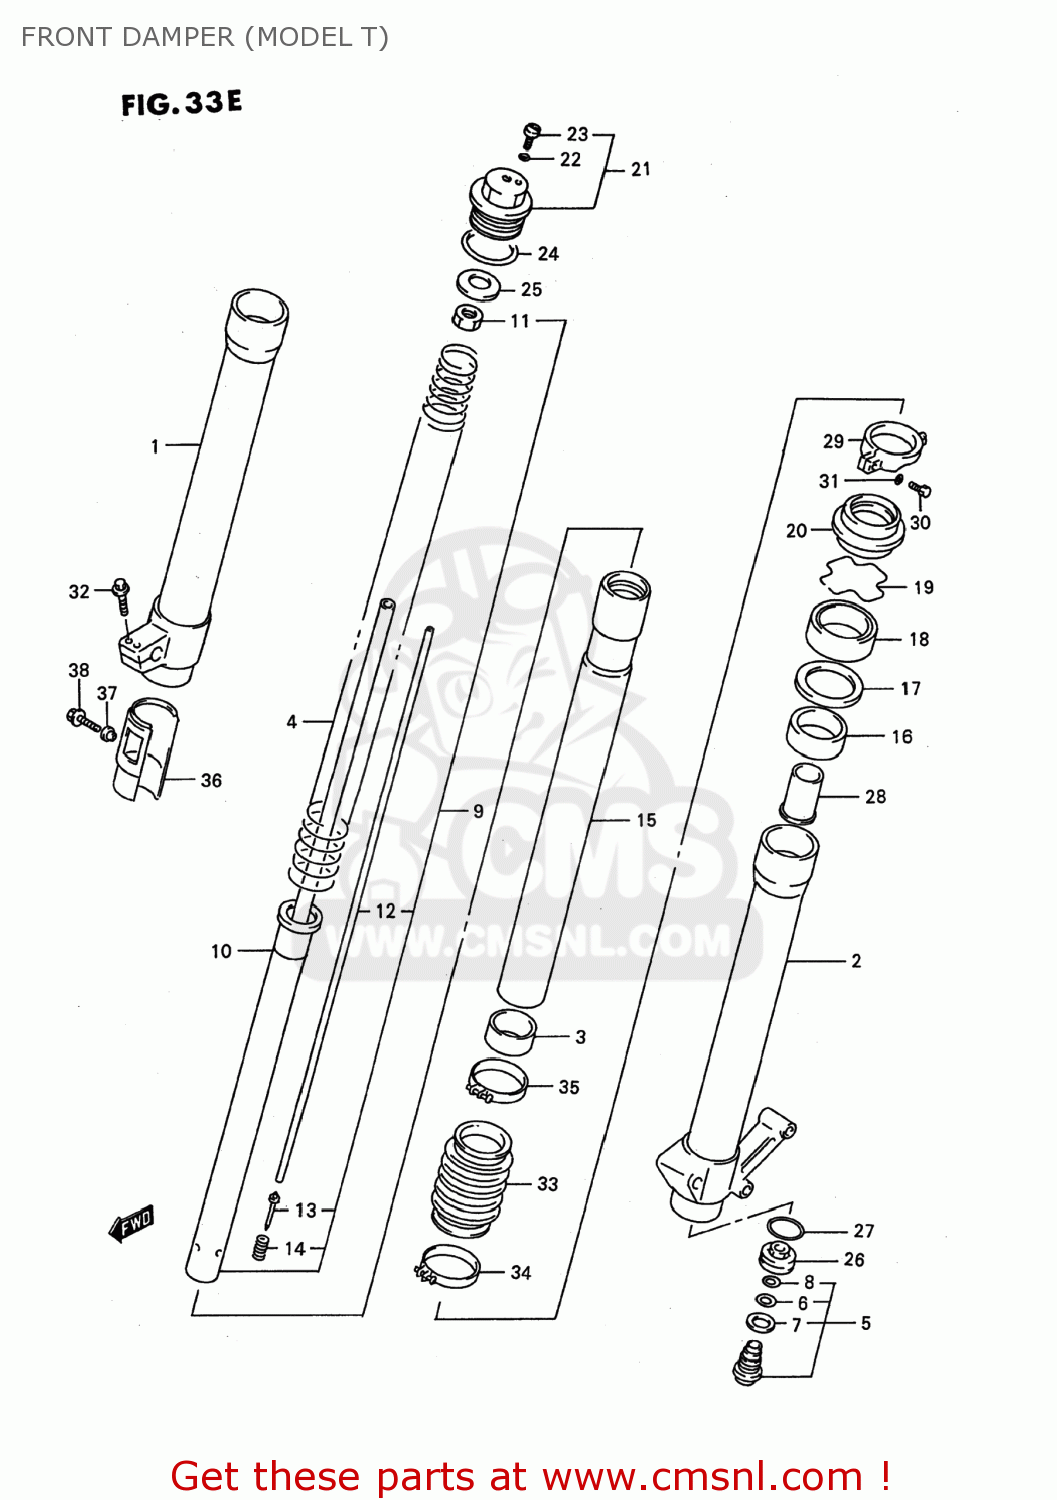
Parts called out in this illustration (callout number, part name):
1	TUBE,OUTER,RIGHT
2	TUBE,OUTER,LEFT
3	BUSH,SLIDE
4	SPRING,FR
5	BOLT,CTR
6	O RING,CTR BOLT
7	GASKET (NAS)
8	O RING,CTR BOLT UPR
9	DAMPER,FRONT
10	BUSH,SLIDE
11	NUT
12	ROD,PUSH
13	NEEDLE
14	SPRING,PUSH ROD
15	TUBE,INNER
16	BUSH,GUIDE
17	SPACER,SEAL
18	SEAL,OIL
19	RING,OIL SEAL STOPPER
20	SEAL,DUST
21	BOLT,FORK
22	O RING,PLUG
23	BOLT,PLUG
24	O RING
25	JOINT,SPRING
26	PLATE,END
27	O RING,FORK BOLT
28	PIECE,OIL LOCK
29	HOLDER
30	BOLT
31	WASHER (5.3X10X1.0)
32	BOLT
33	BOOT
34	CLAMP
35	BAND,BOOT
36	PROTECTOR,OUTER TUBE,RIGHT
37	WASHER
38	BOLT
